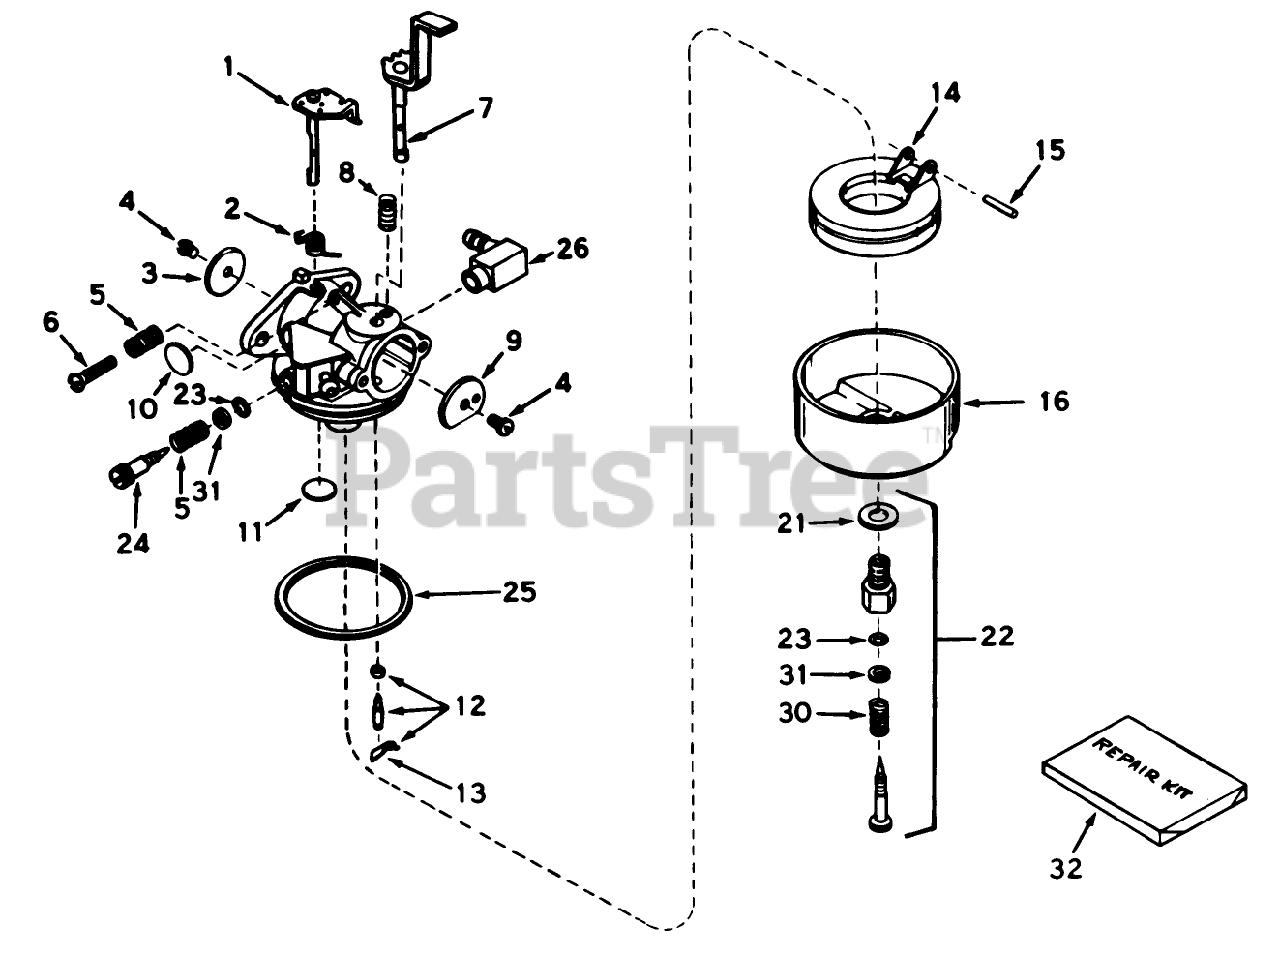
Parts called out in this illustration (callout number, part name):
1	Throttle Shaft and Lever ASM
2	Spring, Throtte Return
3	Shutter-Throttle
4	Screw-Shutter
5	Spring-Tension
6	Screw-Throttle Crack Screw / Idle Speed
7	Shaft Lever Assy., Choke
8	Spring-Positioning, Choke
9	Shutter-choke
10	Plug-Welch, Idle Mixture Well
11	Plug-Welch, Atmospheric Vent
12	Inlet Needle, Seat Clip Assy. (Incl. No. 13)
13	Clip-Spring
14	Float
15	Shaft-Float
16	Bowl-Float (no drain)
21	Washer-Bowl Nut
22	Adjustment Screw Assy., Main (Incl. Nos. 5A, 21 23)
23	ORing
24	Screw, Idle Adj.
25	O Ring-Bowl, Float
26	Fitting-Fuel
30	Spring
31	Washer
32	Repair Kit (Incl. items marked *)
